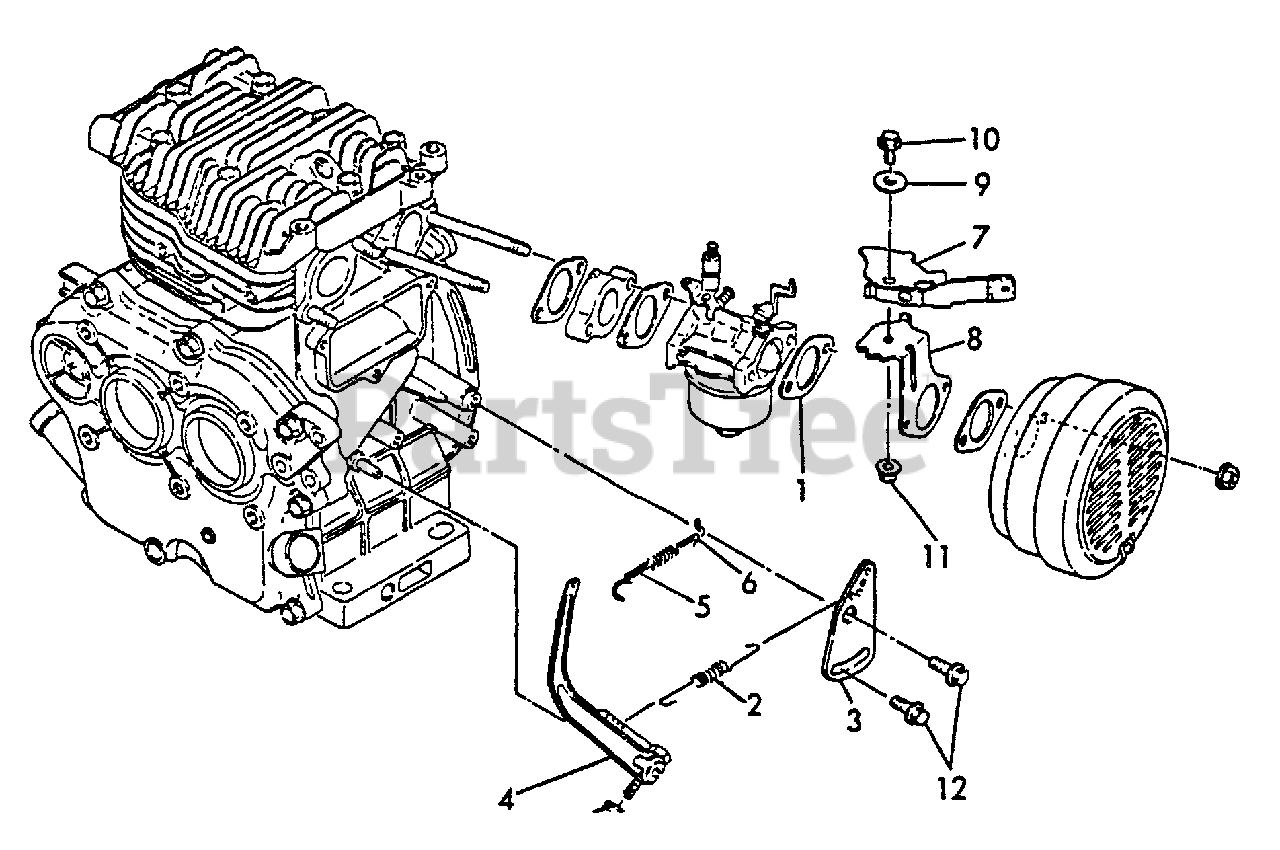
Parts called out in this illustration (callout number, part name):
1	GASKET, INTAKE
2	SPRING, REGULATOR
3	HANDLE, REGULATOR
4	LEVER, GOVERNOR
5	LINK, THROTTLE
7	LEVEL ASSY
8	BRACKET, LEVER
9	COLLAR
10	BOLT - 6X12 -- PLATED
11	NUT - 6 -- FLANGE
12	BOLT - 6X8 -- PLATED
